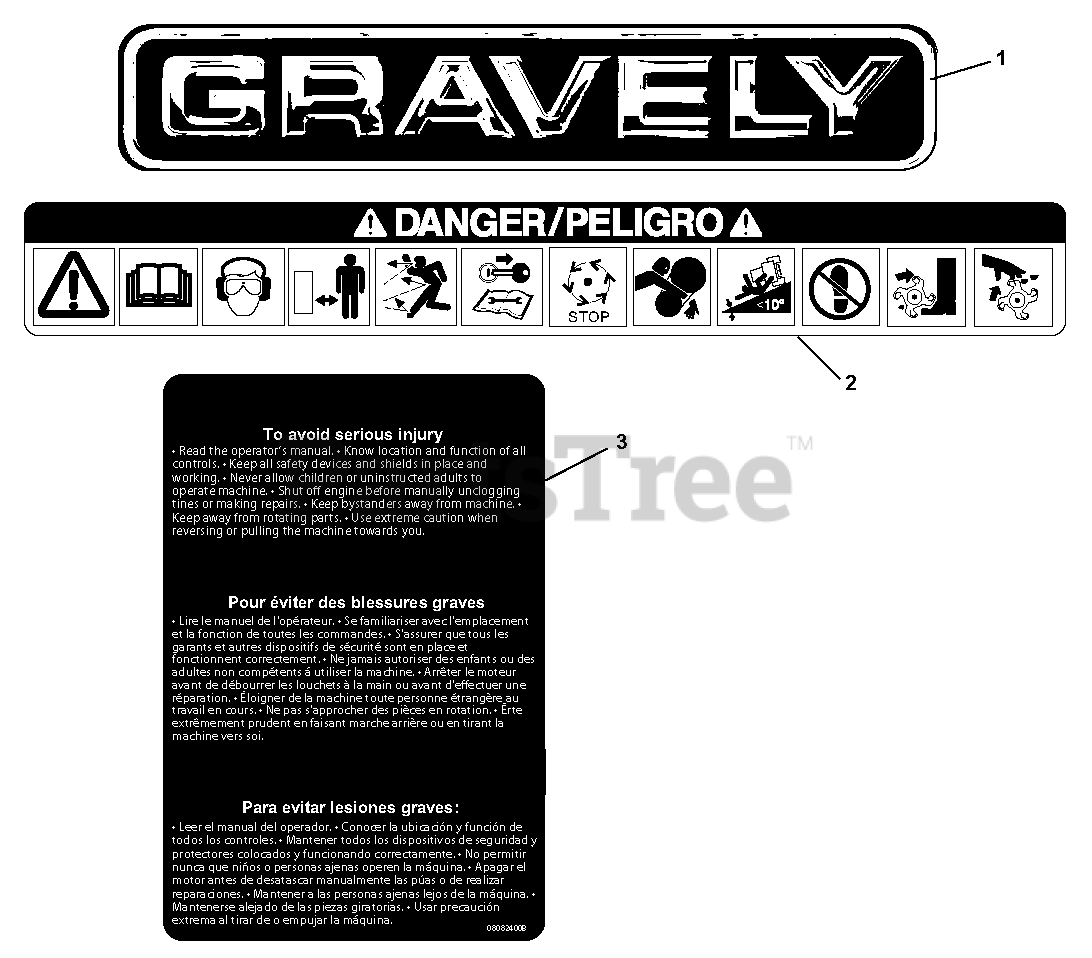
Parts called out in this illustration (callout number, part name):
1	Decal, Gravely
2	Decal, Danger
3	Decal, Warning
